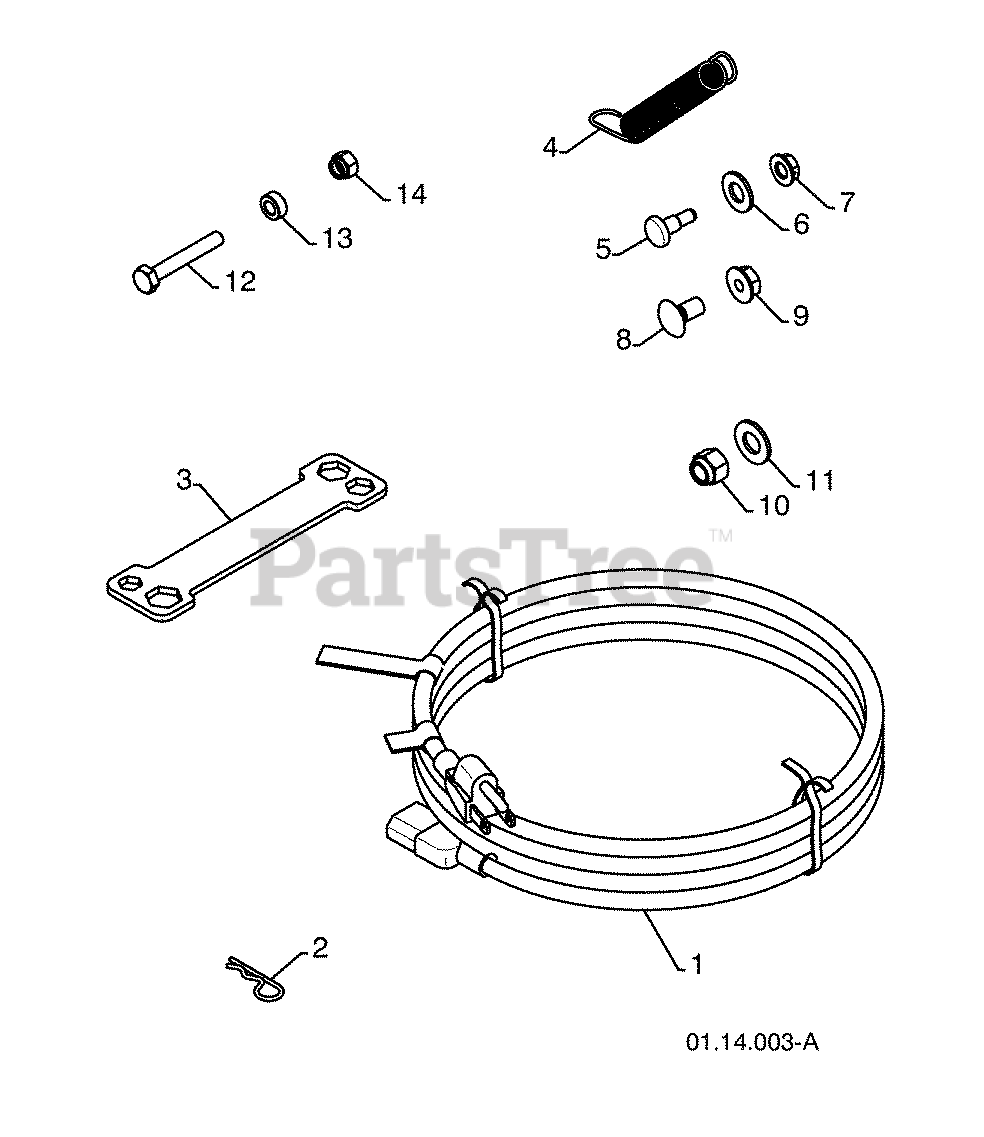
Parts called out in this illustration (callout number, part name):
1	POWER CORD
2	RETAINER PIN
3	WRENCH
4	REMOTE SPRING
5	SHOULDER BOLT 1/4-20
6	NYLON WASHER 1/4-20
7	LOCKNUT 1/4-20
8	CARRIAGE BOLT 5/16-18 X 5/8
9	LOCKNUT 5/16-18
10	LOCKNUT 3/8-16
11	WASHER 3/8
12	SHEAR BOLT 1/4-20 X 1-3/4
14	LOCKNUT 1/4-20
